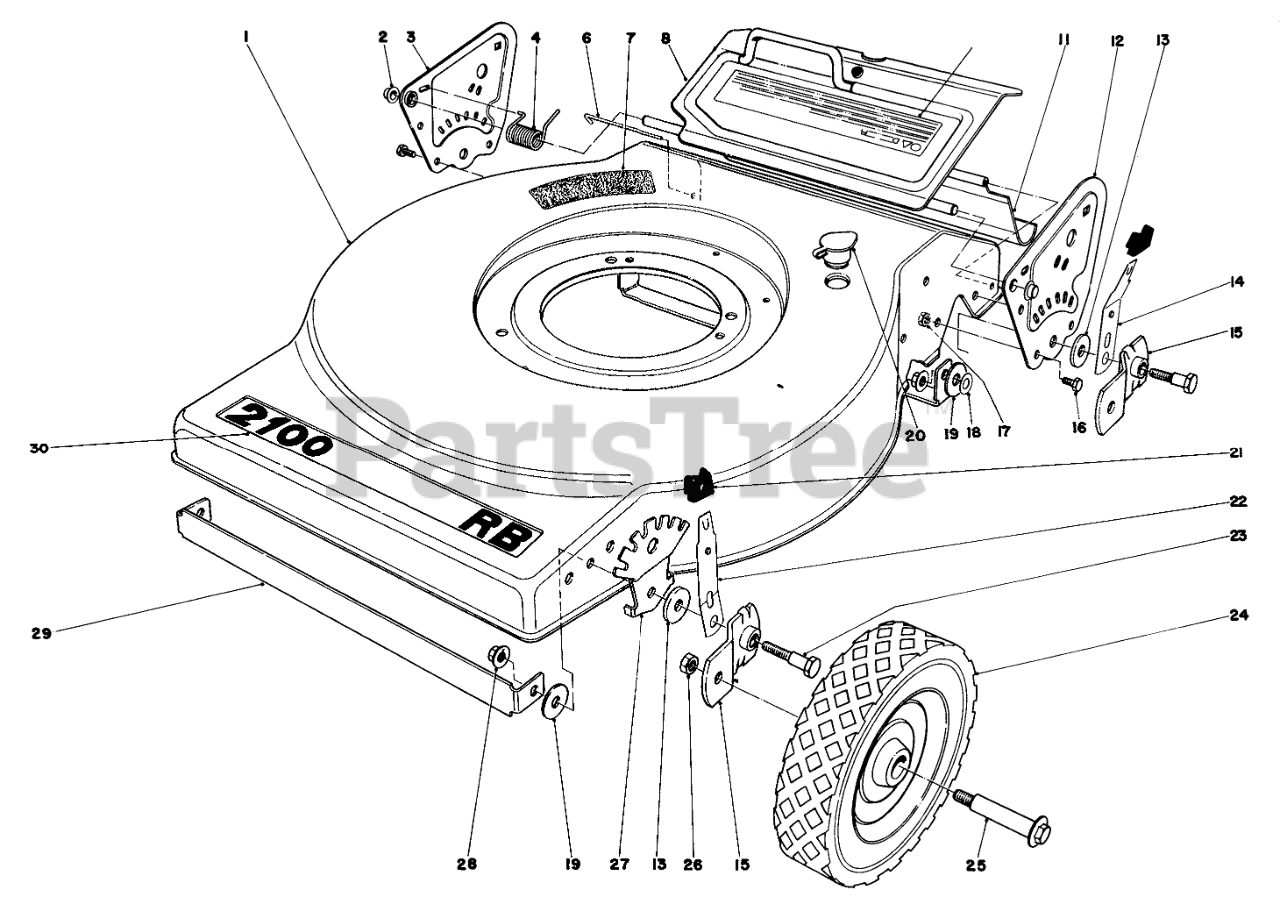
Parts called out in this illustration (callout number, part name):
1	Housing
2	RETAINER-PUSH ON
3	Side Plate R.H.
4	TORSION SPRING
6	SHIELD ROD
7	Step Pad
8	Rear Door
10	Decal-Danger
11	SAF SHIELD REAR
12	Side Plate L.H.
13	PIVOT WASHER
14	Spring Arm
15	PIVOT ARM ASM A
16	SCREW-HH
17	NUT-LOCK, CONE
18	WASHER-PLAIN
19	WASHER
20	WASHOUT PLUG
21	KNOB-ARM
22	SPRING ARM ASM
23	PIVOT SCREW
24	Wheel & Tire Assembly
25	BOLT-WHEEL
26	Nut
27	Quadrant
29	DECK SUPPORT
30	Decal-Deck
